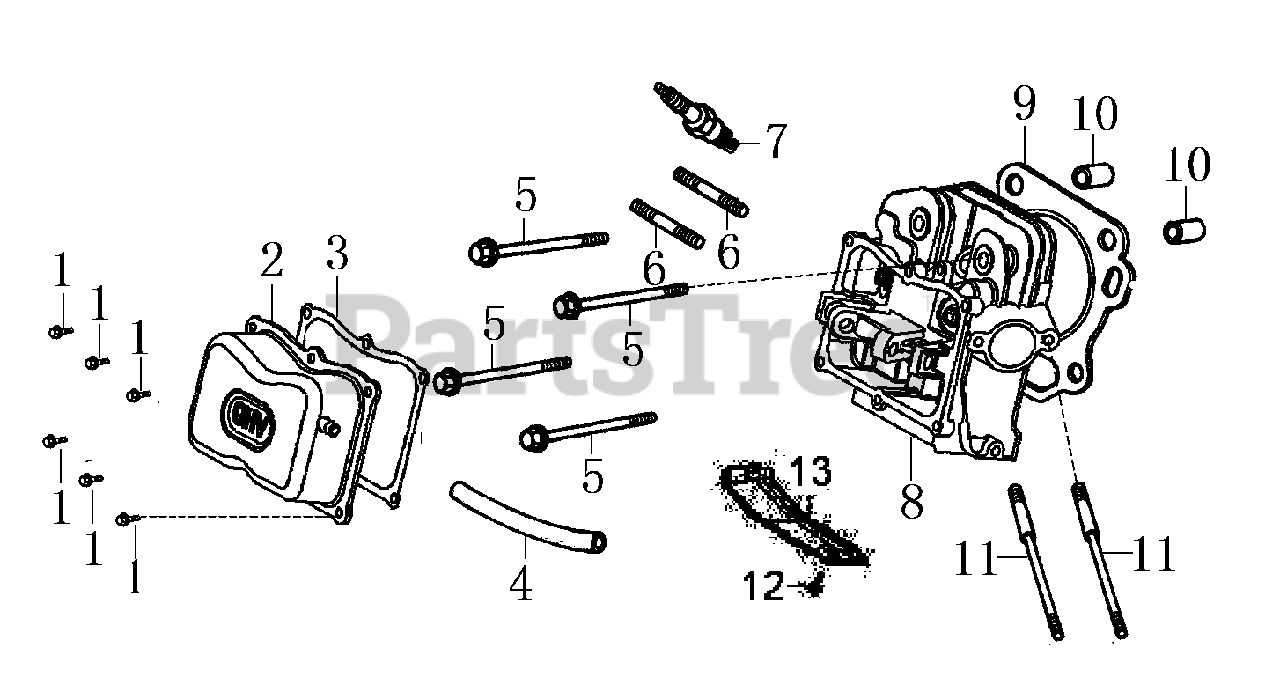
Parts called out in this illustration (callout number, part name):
1	BOLT, FLANGE
2	COVER, HEAD
3	GASKET, HEAD COVER
4	TUBE, BREATHER
5	BOLT, FLANGE, 10X80
6	BOLT, STUD, EXHAUST
7	SPARK PLUG
8	CYLINDER HEAD
9	GASKET, CYLINDER
11	BOLT, STUD, INTAKE
12	BOLT, FLANGE M6X12
